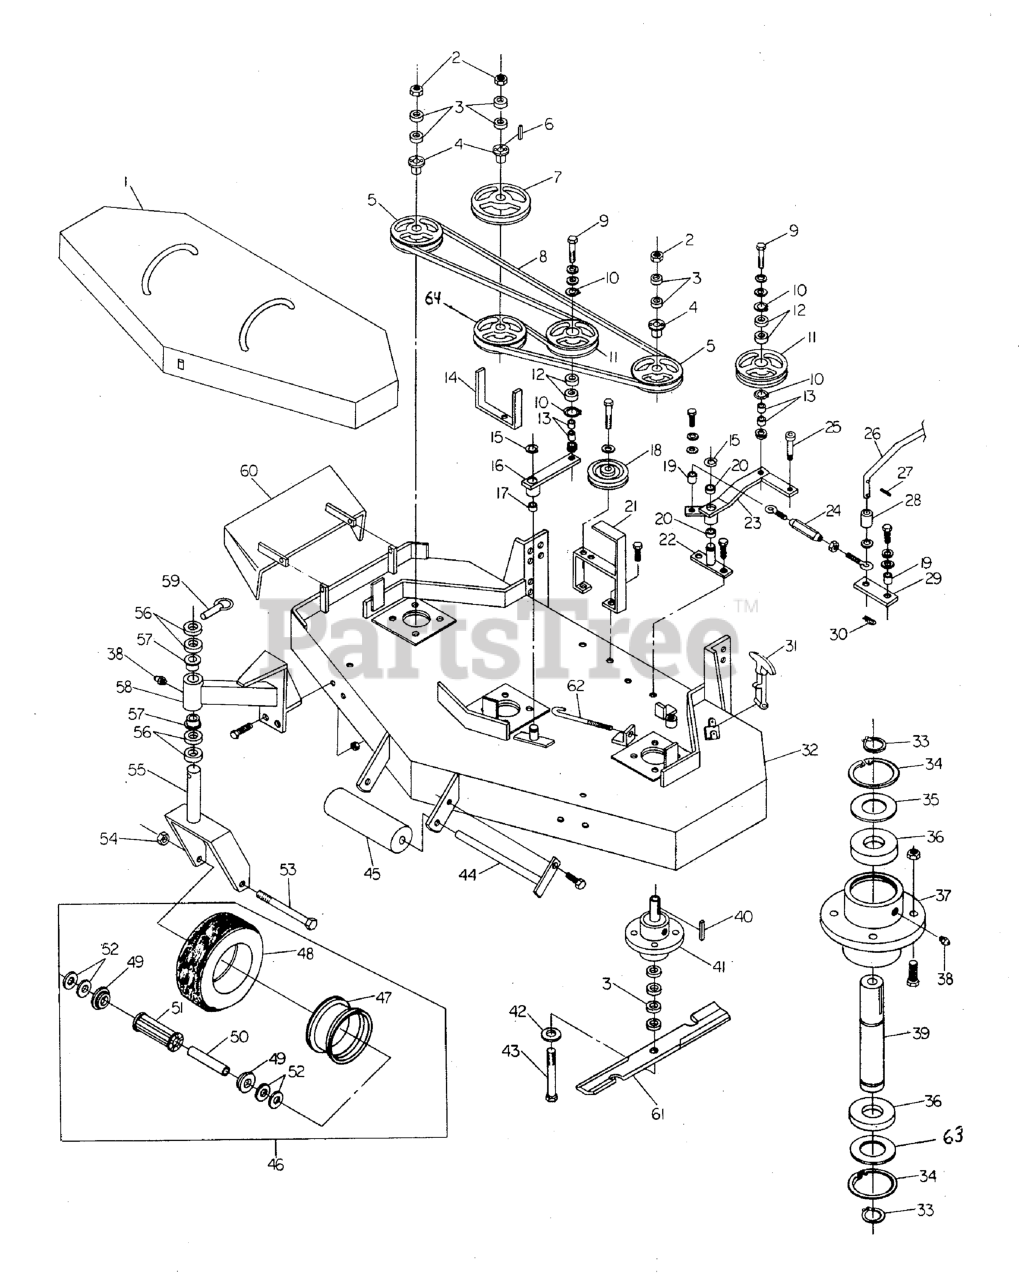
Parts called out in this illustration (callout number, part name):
1	61" DECK GUARD
1	48" DECK GUARD
2	NUT, 5/8-11 Hex
3	SPACER, .63 x 1.06 x .23
4	BUSHING, Tapered Hub
5	PULLEY, Spindle
6	KEY, 1/4 SQ. X 2
7	PULLEY, Spindle
8	BELT, Blade Spindle
9	BOLT, 1/2-20 X 2-1/4 GD5 CZ
10	SNAP RING, Internal
11	PULLEY, Idler
12	BEARING, BALL 11/16X1-9/16X15/32
13	INSERT, Bearing
14	Belt Guide 61" Deck
14	Belt Guide 48" Deck
15	C-CLIP
16	IDLER ARM
17	BUSHING, Brass
18	Idler Pulley
20	BUSHING, Brass
21	Idler Pulley Weldment
22	IDLER MOUNT
23	Idler Arm Weldment
24	Turnbuckle
25	SHOULDER BOLT, 3/8 x 1
26	Linkage Arm
27	COTTER PIN, 3/32" x 1"
28	Caster Support
29	Blade Linkage Bracket
30	HAIRPIN CLIP
31	RUBBER LATCH
32	61" MOWER HOUSING
32	48" MOWER HOUSING
33	SNAP RING, Internal
34	SNAP RING, Internal
35	SPINDLE WASHER, Top
36	BEARING
37	SPINDLE HOUSING
38	GREASE FITTING
39	SPINDLE SHAFT
40	KEY, 1/4 SQ. X 1-1/4
41	SPINDLE ASSEMBLY, Complete
42	WASHER, 5/8" USS
43	BOLT, 5/8-11 x 9-1/2
45	ROLLER
46	Caster Wheel Assembly
47	Caster Wheel Rim Only
48	Caster Wheel Tire Only
49	Bearing Retainer
50	AXLE, Caster Wheel
51	Roller Bearing
52	WASHER, 3/4 SAE
53	BOLT, 1/2-13 x 5
54	NUT, 1/2-13 HEX NYLON LOCK
55	YOKE, Caster
56	SPACER, 1.02 x 1.56 x .50
57	BUSHING, Flange
58	Caster Support
59	PIN, Lynch
60	CHUTE, DISCHARGE WELDMENT
61	MOWER BLADE, 21"
61	MOWER BLADE, 16-1/4"
63	SPINDLE WASHER, Bottom
64	SPINDLE PULLEY
